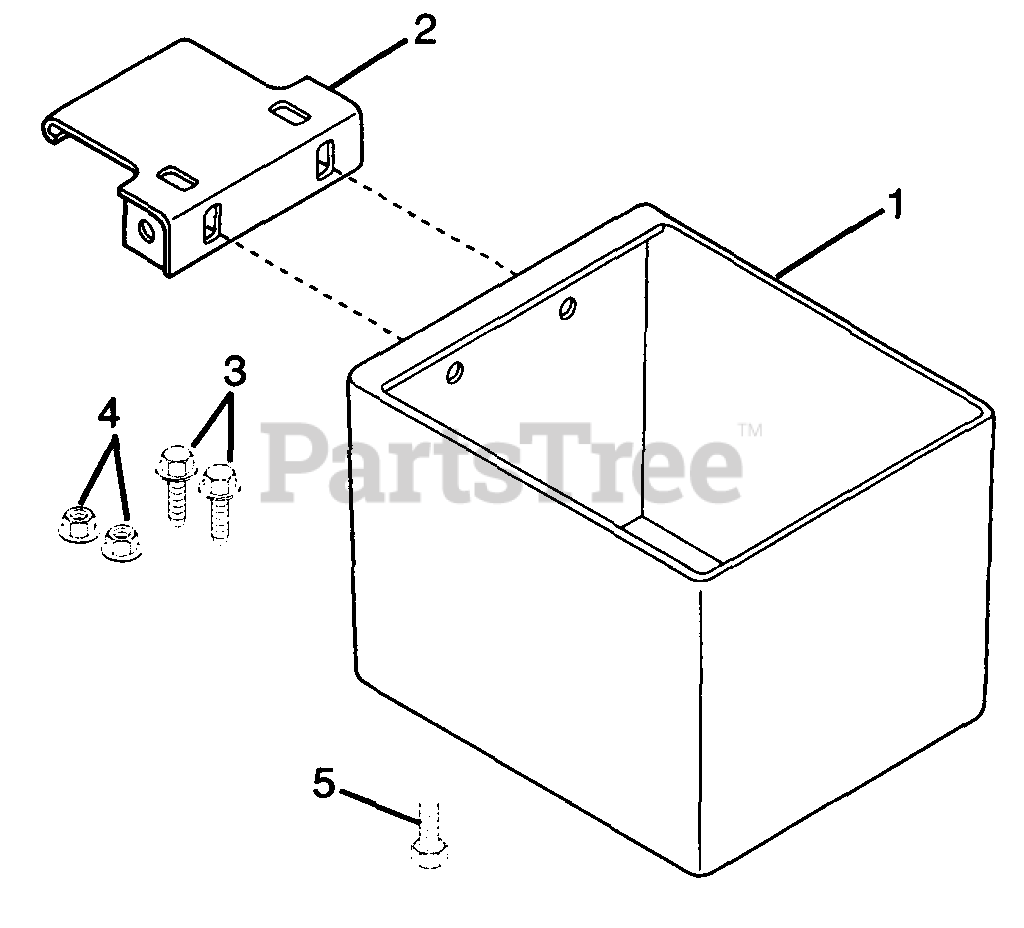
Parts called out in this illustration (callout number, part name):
1	WEIGHT BOX
2	MOUNT HOOK
3	BLT-SERHFWH .31-18X.62 PL
4	NUT-FLG. .312-18 PL
5	BLT-HEX .50-13X.75 GR2
